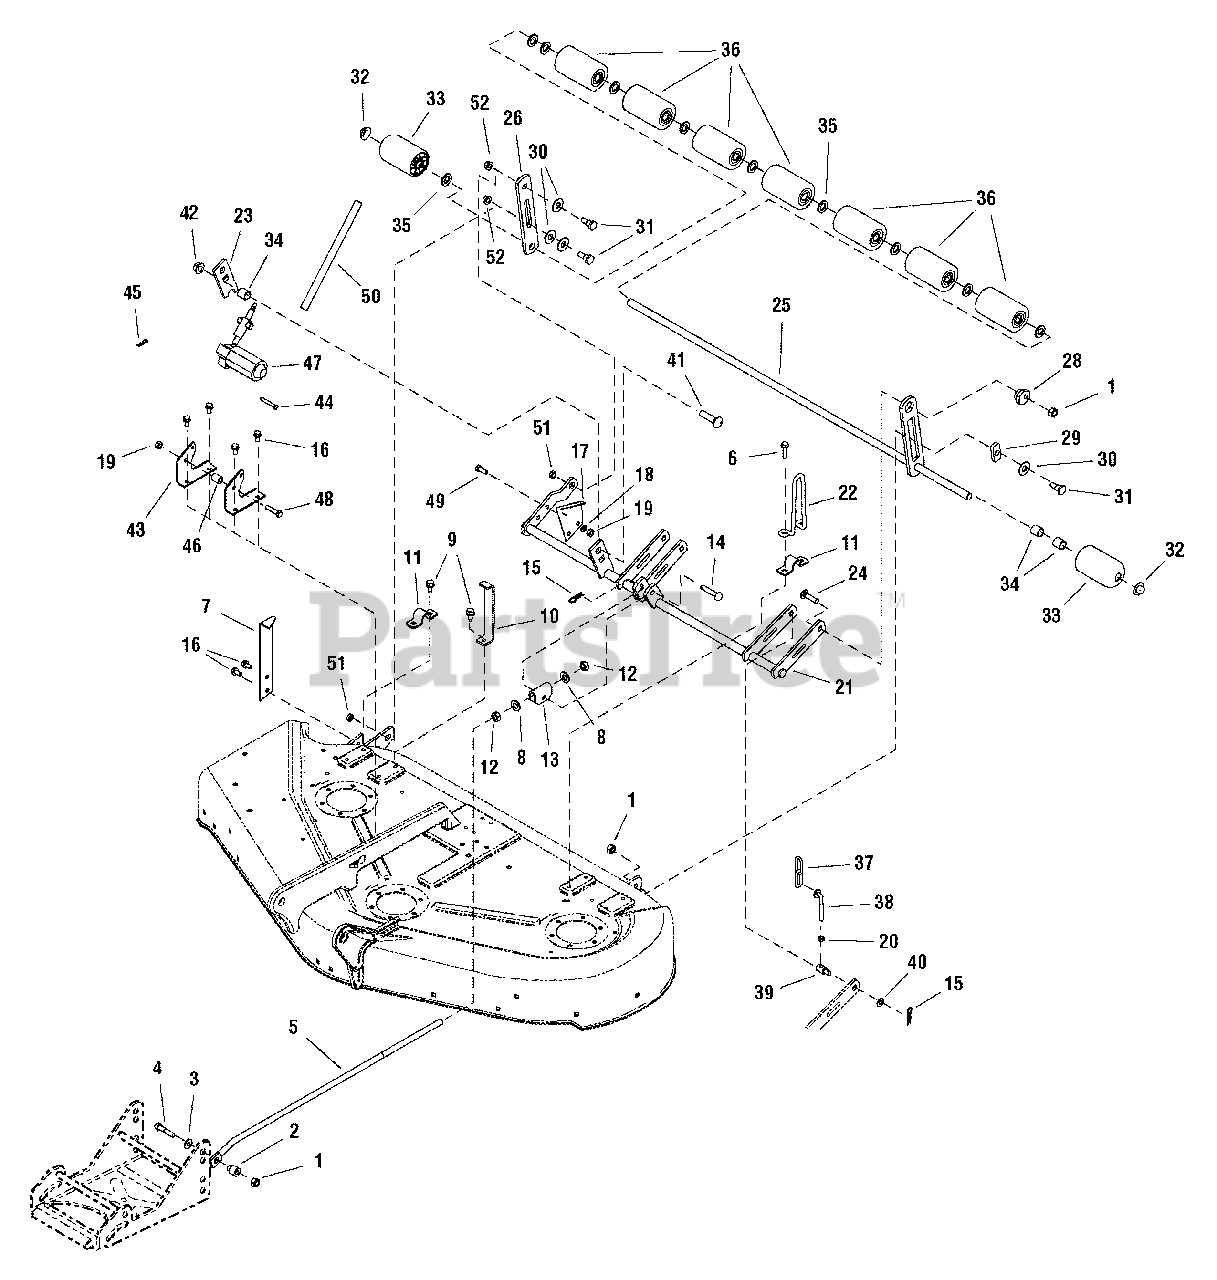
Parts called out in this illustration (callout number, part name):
1	NUT, Hex Toplock Spiral Lock Flange 3/8-16
2	SPACER, 3/8 x 3/4 x 15/16
3	WASHER, 3/8
4	CAPSCREW, Hex Head, 3/8-16 x 1-3/4
5	ROD, Adjustment
6	SCREW, Hex Washer Head Taptite 5/16-18 x 1-1/4
7	INDICATOR, Cutting Height
8	WASHER, 1/2
9	SCREW, Hex Washer Head Taptite 5/16-18 x 3/4
10	BRACKET, Up-Stop
11	STRAP, Roller
12	NUT, Hex Jam 1/2 Jam 1/2-13
14	PIN, Round Head Drilled 3/8 x 2
15	CLIP, Hair Pin
16	SCREW, Hex Washer Head Taptite 5/16-18 x 5/8
17	BRACKET, Height of Cut
18	LOCKWASHER, Spring 5/16
19	NUT, Hex 5/16-18
20	NUT, Hex Jam 5/16-18
21	SHAFT ASSEMBLY, Rocker 44"
22	UP, Stop, 6-1/4 High
23	ARM, Rear
24	CARRIAGE BOLT, 3/8-16 x 1-1/2 G5
25	SHAFT/BAR ASSEMBLY, Roller 44"
26	BAR, Roller 5/16
28	NUT, Hex Adjusting, .99 DIA .687
30	WASHER, 1/2
31	BOLT, Shoulder, 3/8-16 X 1.34
32	NUT, Push for 5/8 Diameter Stud Capped
33	ROLLER, Rounded
34	SPACER, .66 ID
35	WASHER, 5/8
37	CHAIN, Link
38	ROD, Height Adjusting
40	WASHER, 3/8
41	CARRIAGE BOLT, 1/2-13 x 2 G5
42	NUT, Hex Toplock Flange 1/2-13
43	BRACKET, Mounting
44	PIN, Shear
45	CLIP, Hairpin
46	SPACER, Powdered Metal
47	MOTOR, Electric Mini Actuator
48	CAPSCREW, Hex Head 5/16-18 x 1-1/2 G5
49	CAPSCREW, Hex Head 5/16-18 x 7/8 G5
50	TUBE, Flexible
52	NUT, Hex Flange 3/8-16 Machine Lock Large
